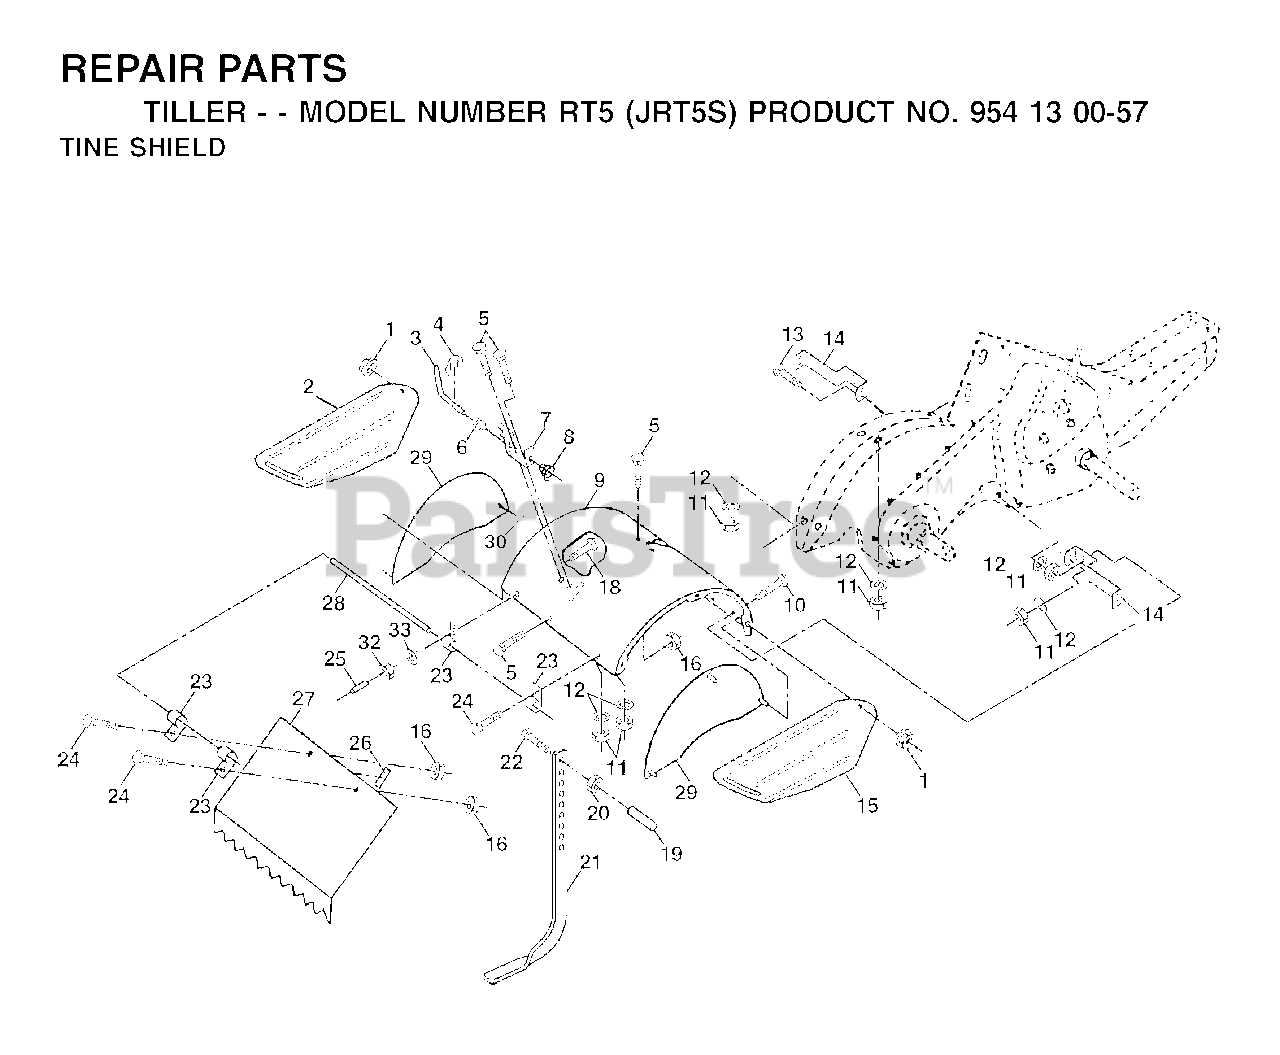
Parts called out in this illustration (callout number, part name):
1	NUT LOCK HEX FLANGE 5/16-18
3	STAKE PIN TI
4	RING, KLIP
5	BOLT
6	SPRING TI
7	LATCH BRACKET TI
8	SPRING CRT
10	BOLT
12	LOCKWASHER
13	BOLT.CARRIAGE.5/16-18
14	BRACKET.TINE.SHIELD.TILLER
16	NUT T
20	NUT.HEX.3/8-16UNC
21	STAKE DEPTH CRT
22	BOLT.375-16
23	HINGE CRT
25	VINYL CAP TI
26	PAD IDLER TI
28	PIN.HINGE.TILLER
30	LOCKNUT-FLANGE 5/16-18
32	NUT
33	LOCKWASHER
